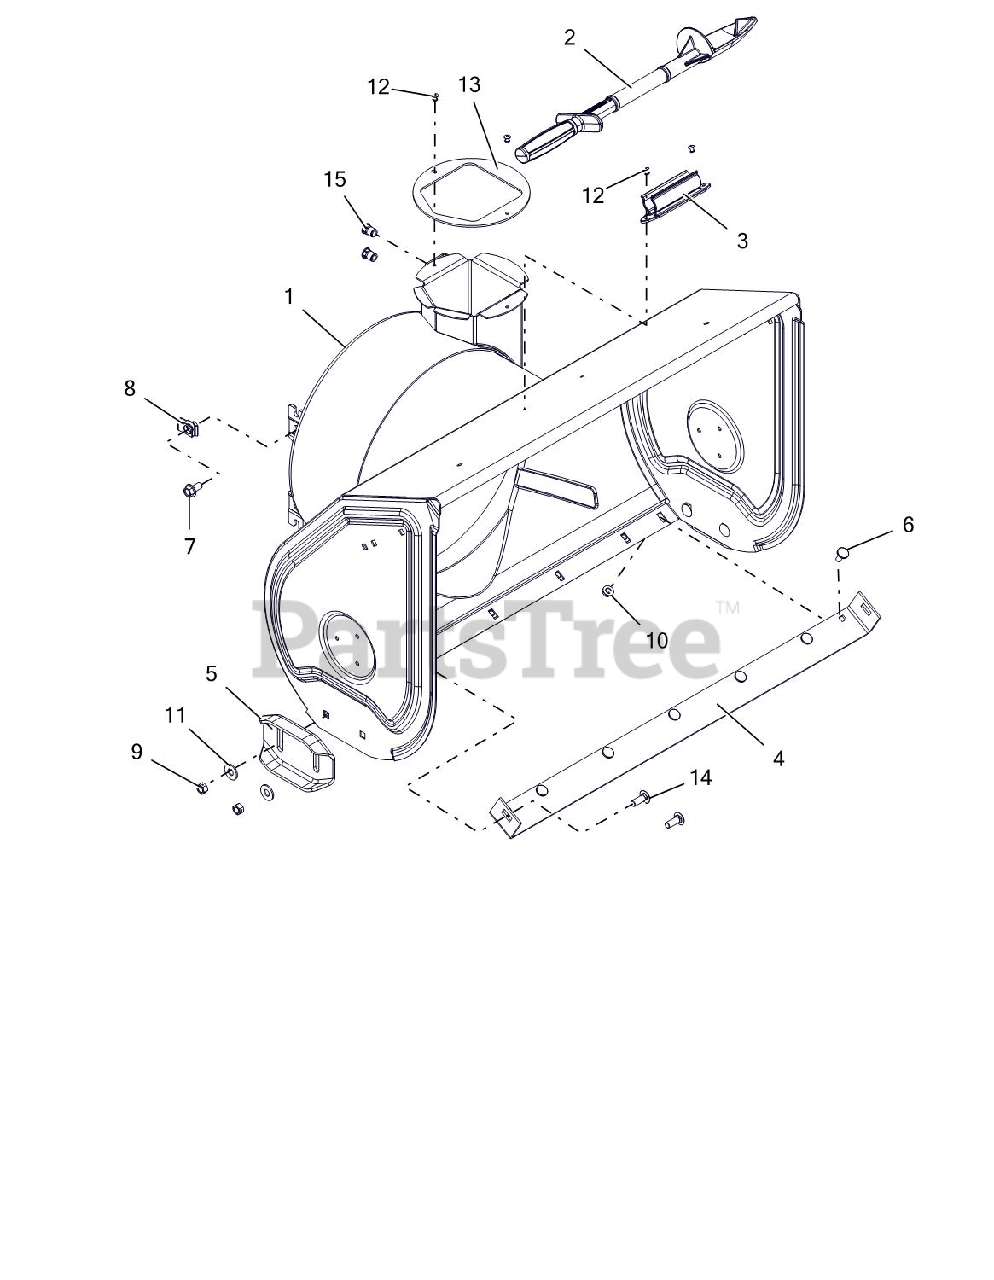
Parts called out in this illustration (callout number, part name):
1	BLOWER HOUSING W/DECAL 30"
2	DEVICE, SNOW CLEAN OUT
3	MOUNT, SNOW CLEAN OUT
4	BLADE, SCRAPER-30"
5	SKID SHOE, REVERSIBLE - ORANGE
6	BOLT, MODIFIED HEAD CARRIAGE
7	BLT-SERHFWH .38-16X.75 YWZC
8	NUT-RTNR .375-16X.37
9	@NUT-LK-CTR .38-16 YWZC
10	@NUT-LK-TOP-FLG .31-18 YWZC
11	@WSHR-FL-STL.438X1.00X.083 YWZ
12	RVT-POP .187 YZ
13	BAFFLE, DISCHARGE NECK
14	@BLT-RDHDSHSQNK.38-16X1.0 G5YZ
15	NUT, THREADED INSERT .38-16
